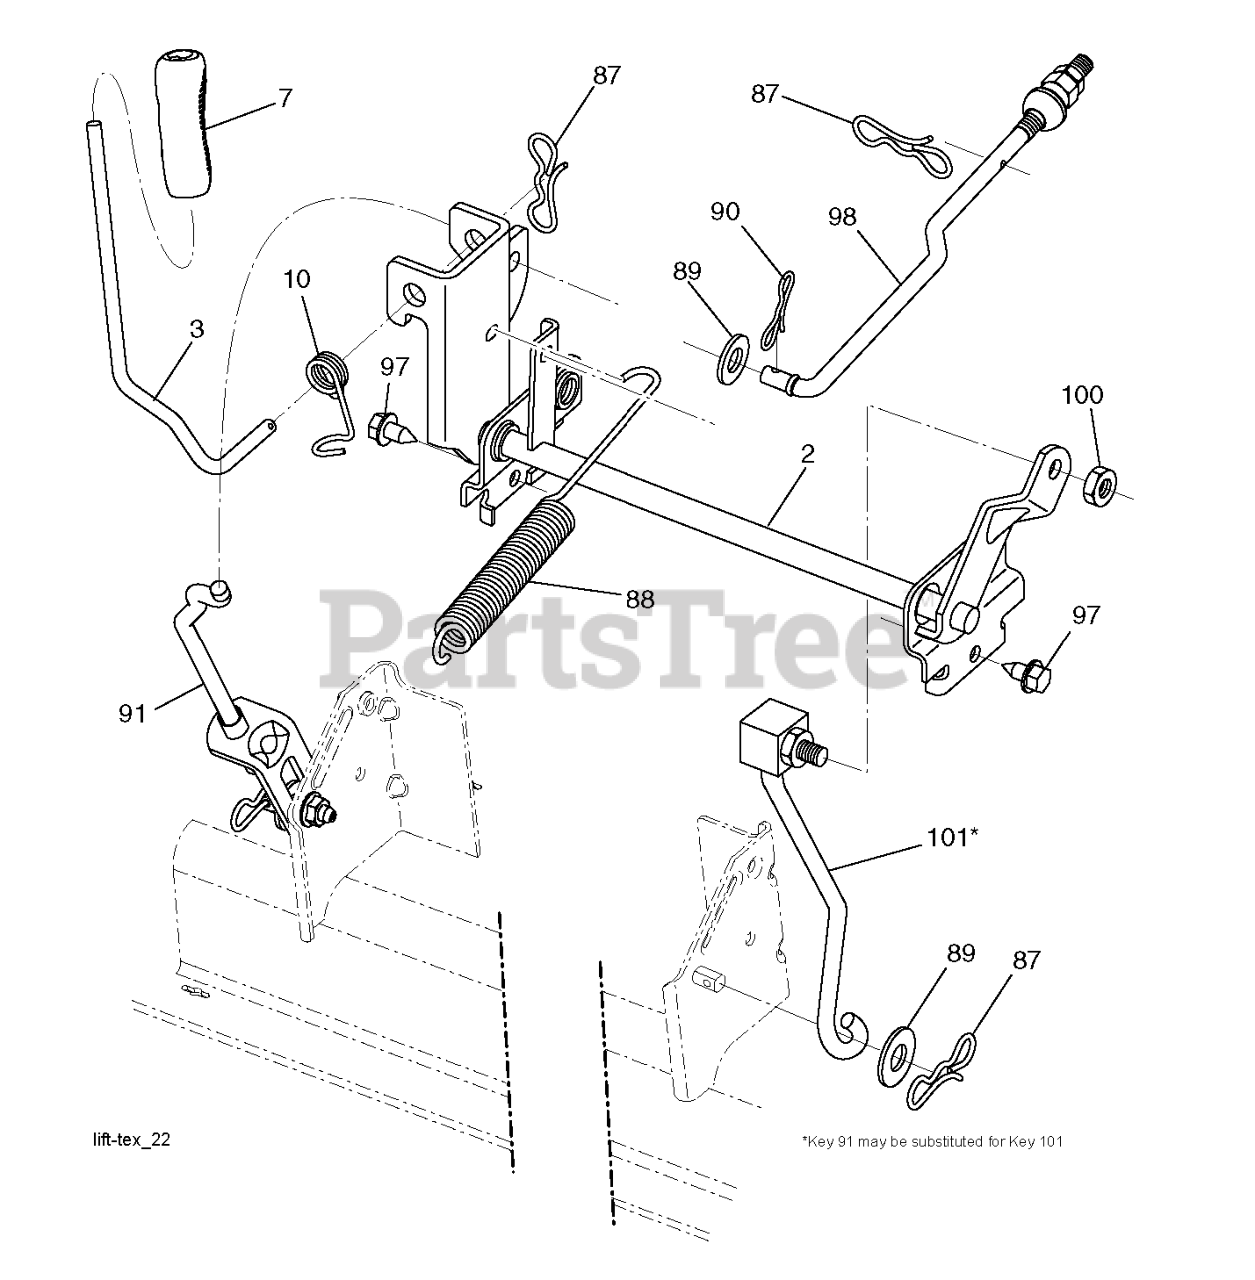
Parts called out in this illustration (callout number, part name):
2	SHAFT.ASM.CROSS.LIFT
3	LEVER.LIFT.HANDLE.LT
7	GRIP.HANDLE.LIFT.PVC.BLACK
10	SPRING.TORSION.LIFT.HANDLE
87	PIN.COTTER.7/16.BOW TI.
88	SPRING.LIFT.ASSIST
89	WASHER.CLEAR.ZINC
90	PIN.COTTER.5/16.BOW TI
91	LINK.ASM.LIFT.REAR
97	SCREW, 3/8-16X3/4
98	LINK.ASM.SUSP.FRONT.MW
100	LOCKNUT
101	LINK.ASM.LIFT.FIXE.38/42/46"
